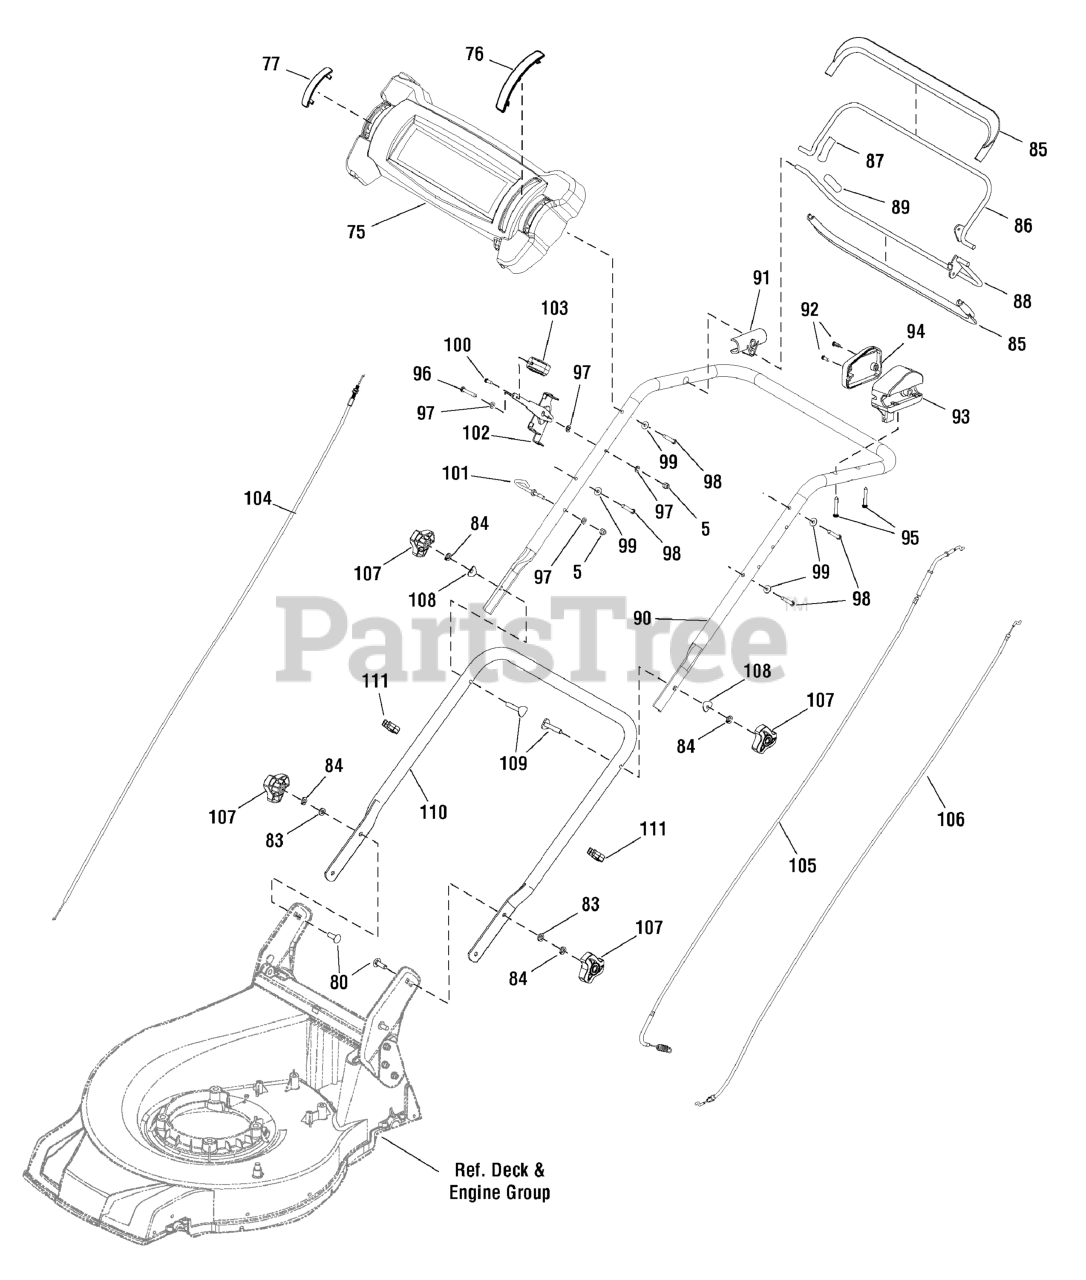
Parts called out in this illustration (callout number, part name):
5	NUT, Hex, Nylon Insert, Torque Type
75	PANEL, Handle Cover
76	INSERT, Throttle Cover
77	INSERT, Throttle Cover
80	BOLT, Carriage,
83	WASHER, Flat, C Class
84	WASHER, Spring
85	COVER, Handle
86	LEVER, Brake
87	COVER, Brake Lever
88	LEVER, Clutch
89	COVER, Clutch Lever
90	HANDLE, Upper
92	SCREW, Pan Head, Cross Recessed Tapping
93	CABLE BOX, Control Lever
94	COVER, Cable Box
95	SCREW, Pan Head, Cross Recessed Tapping
96	SCREW, Pan Head, Cross Recessed, H-Form
97	WASHER, Flat, C Class
98	SCREW, Pan Head, Cross Recessed Tapping
99	WASHER, A-Form
100	SCREW, Pan Head, Cross Recessed Tapping
101	HOOK, Start Rope
102	FRAME, Throttle
103	GRIP, Throttle
104	CABLE, Throttle
105	CABLE, Clutch
106	CABLE, Brake
107	KNOB, Lock
108	WASHER, Curved
109	BOLT, Connecting
110	HANDLE, Lower
111	CLIP, Cable
